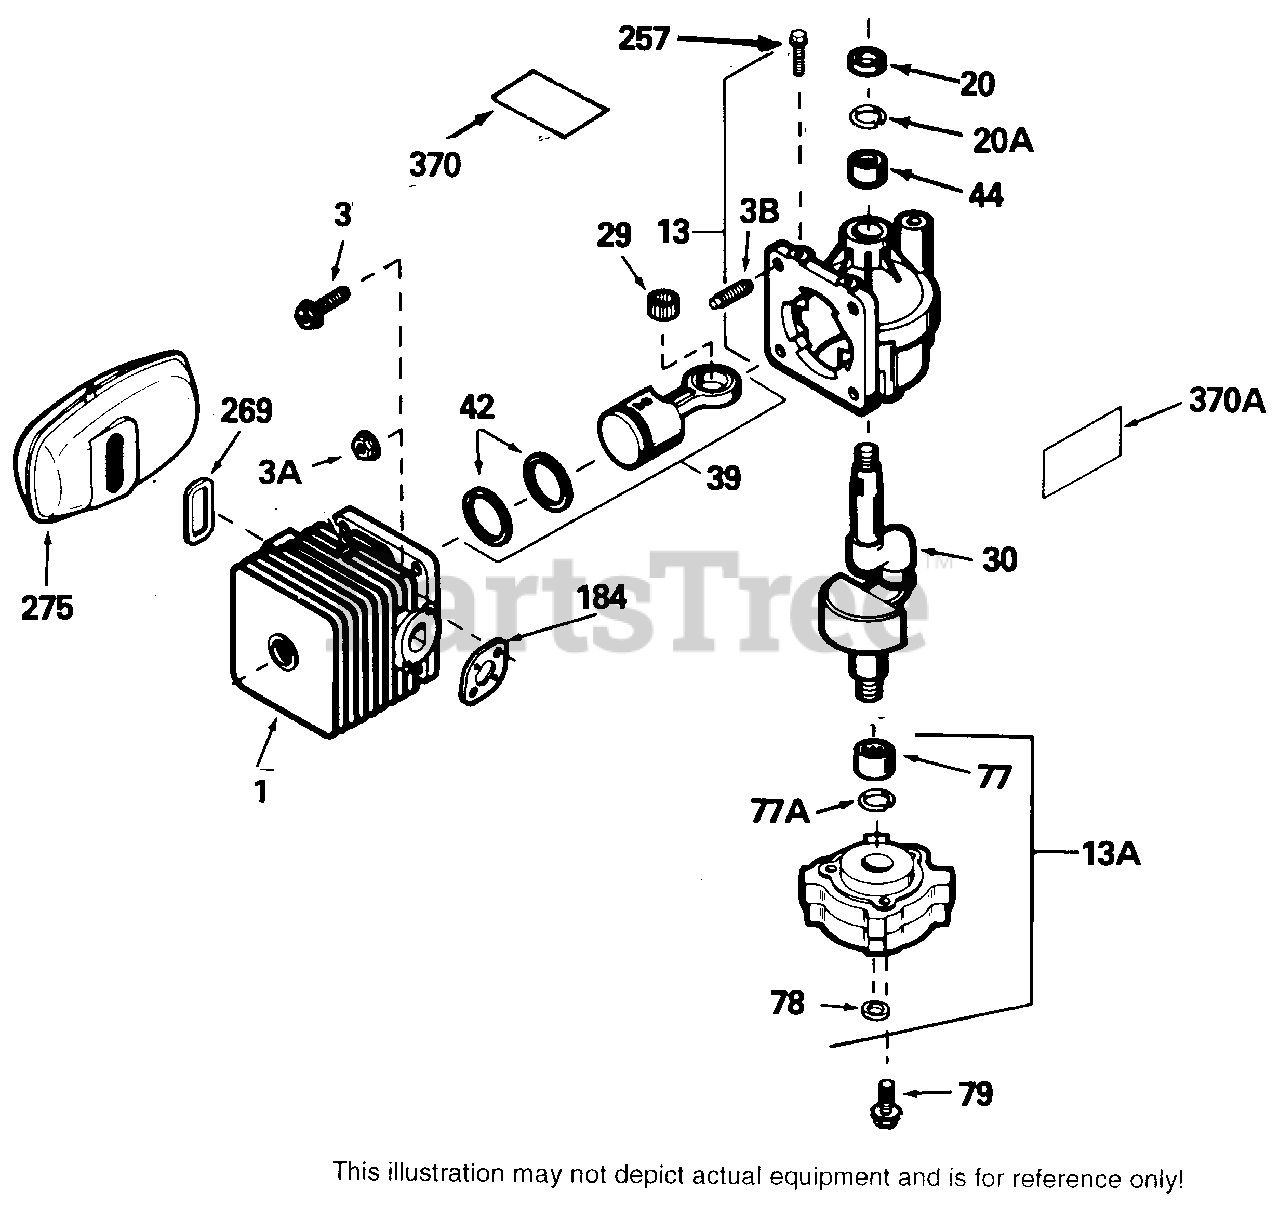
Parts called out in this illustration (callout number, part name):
1	"Cylinder NOTE: When this part is no longer available, a new short block m ust be ordered.
3A	Nut, Flange whiz-lock, 1/4-20
3B	Stud, Cylinder
13	Crankcase Assy. (Incl. 3B, 20, 20A & 44) NOTE: When this part is no l onger available, a new short block mu st be ordered.
13A	Cover Assy., Crankcase (Incl. 77, 77A & 78) NOTE: When this part is no l onger available, a new short block mu st be ordered.
20	Seal, Oil
20A	Retainer, Bearing Not used in early p roduction
29	Bearing Set, Needle
30	Crankshaft
39	Piston & Rod Assy. (Incl. 29 & 42)
42	Ring Set, Piston
44	Bearing, Cartridge
77	Bearing, Cartridge
77A	Bearing Retainer (Not in early prod.)
78	Seal, Oil
79	Screw, 1/4-20 x 3/4"
184	Gasket, Adapter
269	Gasket, Exhaust
